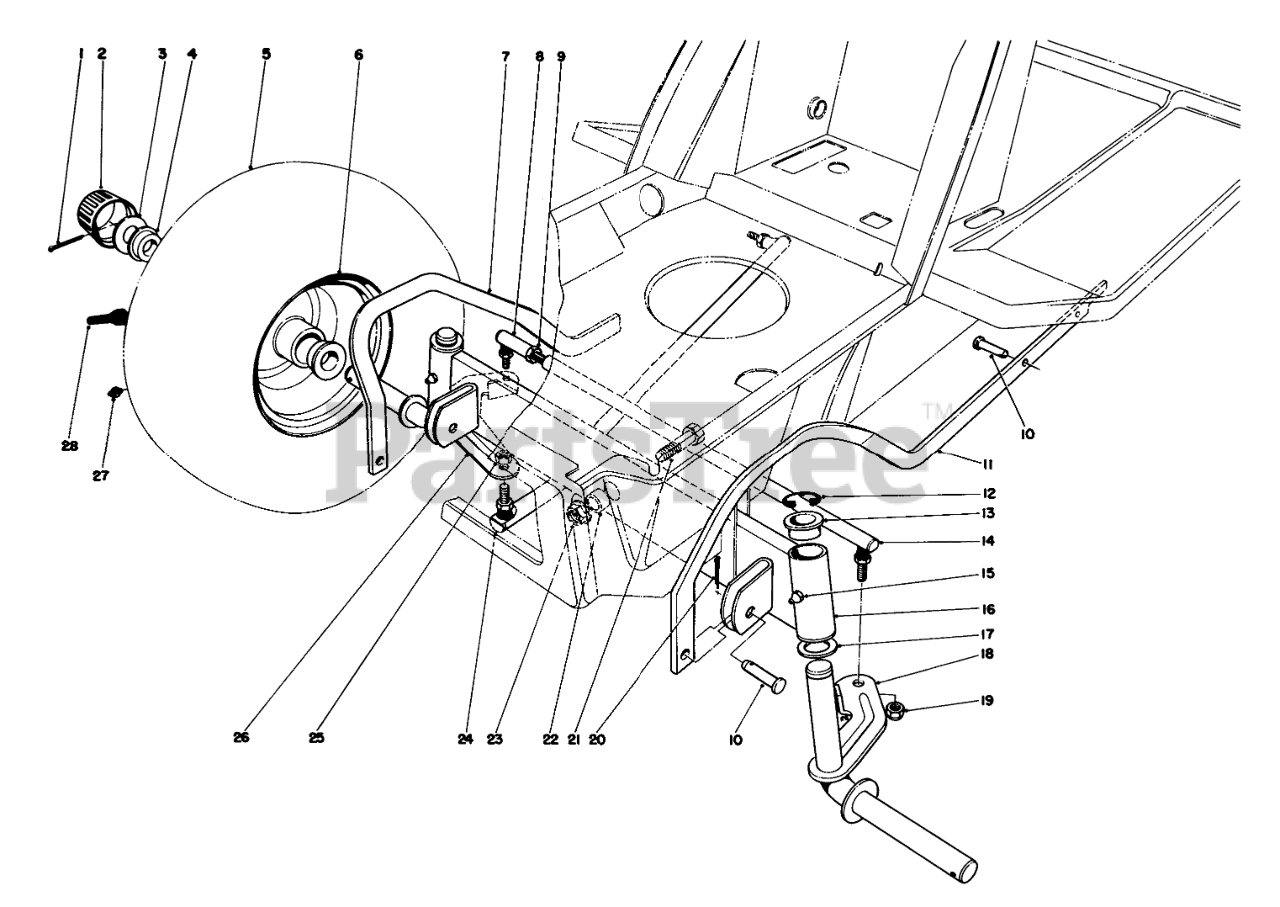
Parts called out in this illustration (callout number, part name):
1	PIN-COTTER
2	Cap-Hub
3	WASHER-PLAIN
4	Bearing
5	TIRE-FRONT
6	FRONT WHEEL
7	RH DECK PARALLEL LINK R
8	JOINT-BALL
9	NUT-JAM
10	PIN-CLEVIS
11	LH DECK PARALEL LNKR
12	E-RING
13	BEARING-FLANGE
14	Tie Rod Steering (Incl. Ref. #8 & 9)
15	GREASE FITTING
16	Front Axle (Incl. Ref. #13)
17	WASHER-THRUST
18	Spindle L.H.
19	NUT-LOCK, NI
20	PIN-COTTER
21	SCREW-HH
22	SPACER-AXLE, FRONT
23	NUT-HF
24	STEERING ARM B
25	NUT-HEX
26	SPINDLE WA RH B
27	FITTING-GREASE
28	STEM-VALVE
